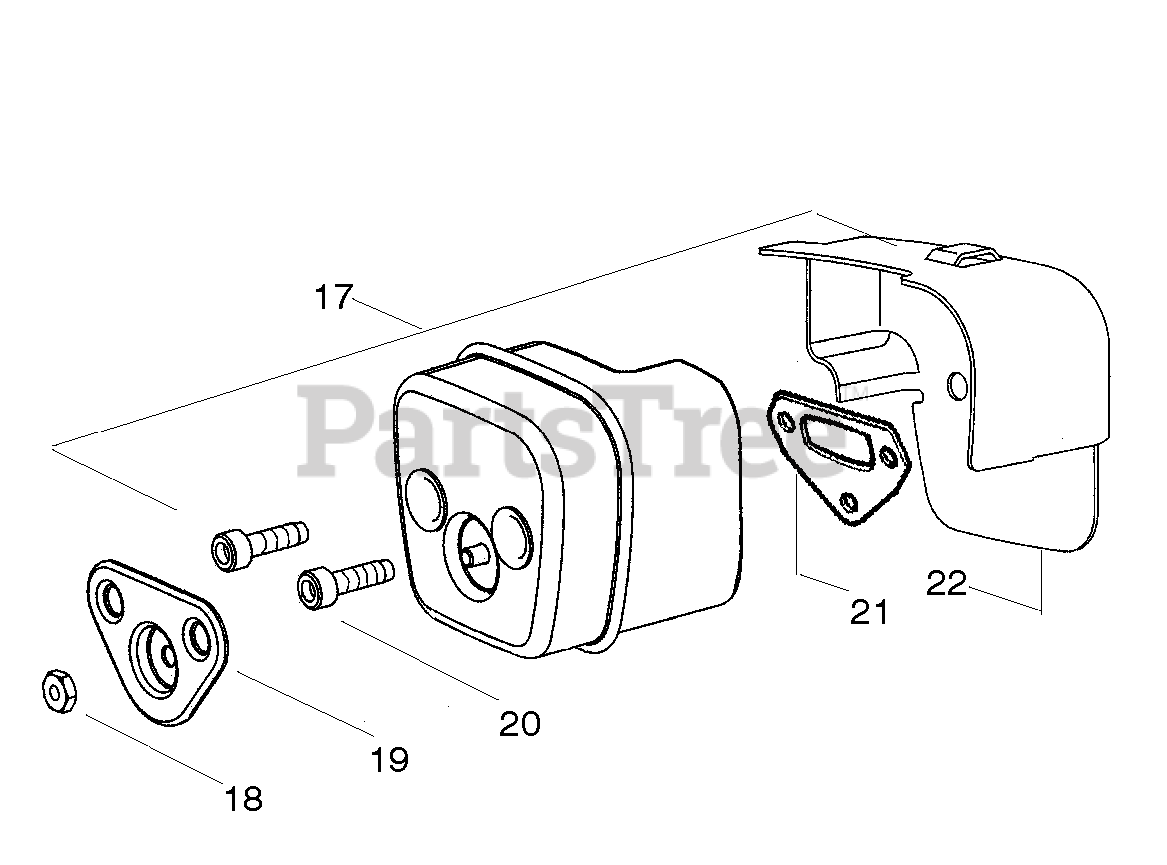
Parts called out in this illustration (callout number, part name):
17	MUFFLER KIT
18	NUT-BRASS
19	COVER BOLT
20	SCREW MUFFLER
21	GASKET-MUFFLER
22	BACKPLATE, MUFFLER
